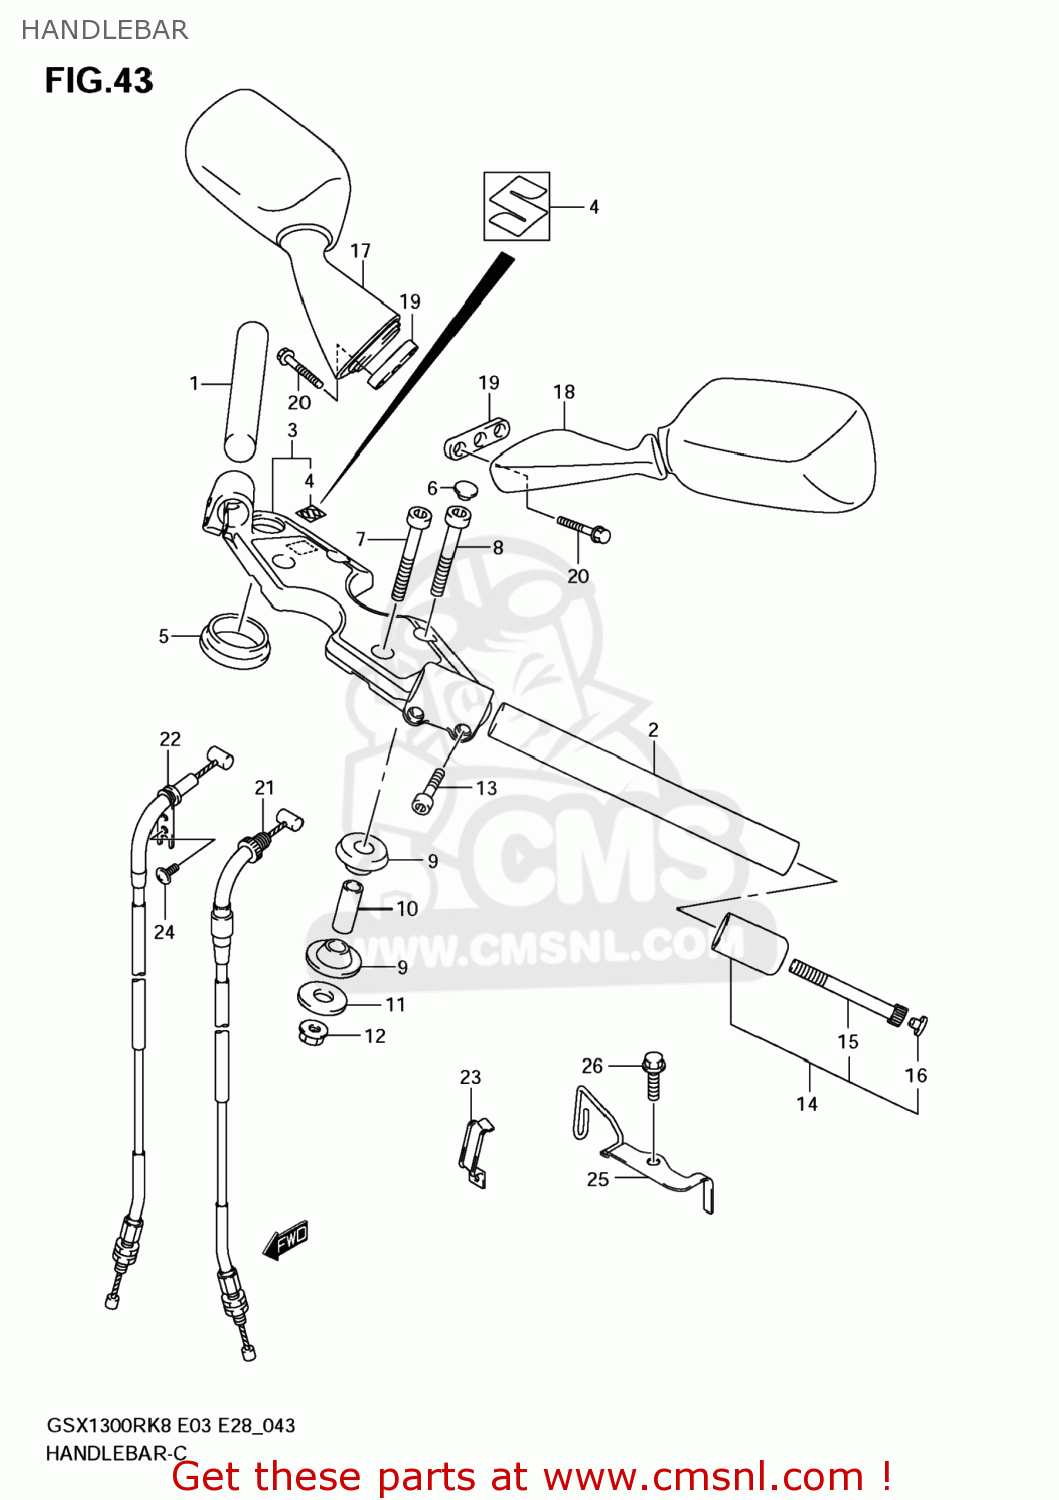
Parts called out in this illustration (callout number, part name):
1	HANDLEBAR,R
2	HANDLEBAR,L
3	HOLDER,HANDLEBAR
4	EMBLEM,S
5	CUSHION,HANDLE HOLDER
6	CAP,HANDLE HOLDER BRACKET BOLT
7	BOLT
8	BOLT
9	CUSHION,UPR BRACKET
10	SPACER,STEERING STEM HEAD
11	WASHER(10.5X30X3.2)
12	NUT
13	BOLT(6X25)
14	BALANCER SET,HANDLEBAR
15	BOLT
16	CAP(OD:10)
17	MIRROR ASSY,RR VIEW,R
18	MIRROR ASSEMBLY,REAR VIEW
19	CUSHION,RR VIEW MIRRORR
20	BOLT
21	CABLE ASSY,THR
22	CABLE ASSY,THR
23	GUIDE,CABLE
24	SCREW(5X10)
25	GUIDE,CABLE
26	BOLT
